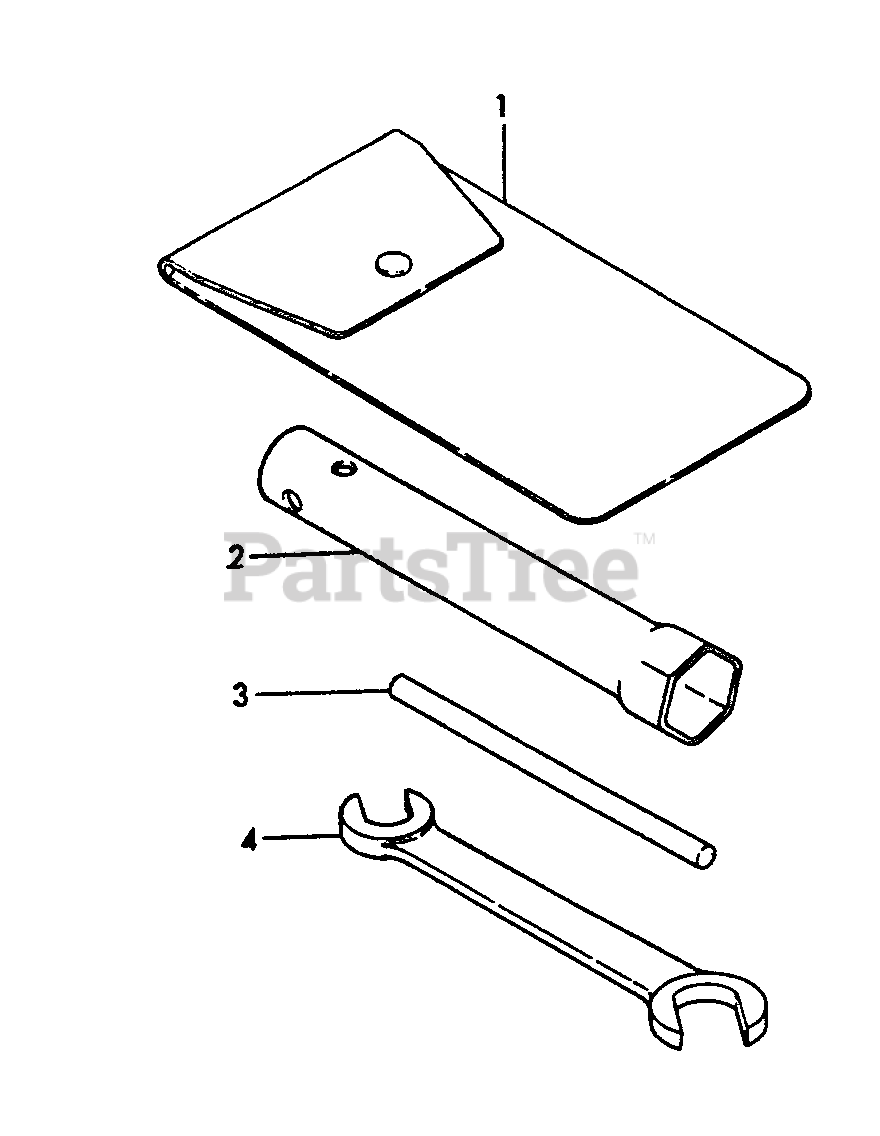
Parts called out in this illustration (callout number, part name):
1	BAG, TOOL
2	BOX SPANNER - 21
3	BAR
4	WRENCH 10×12
